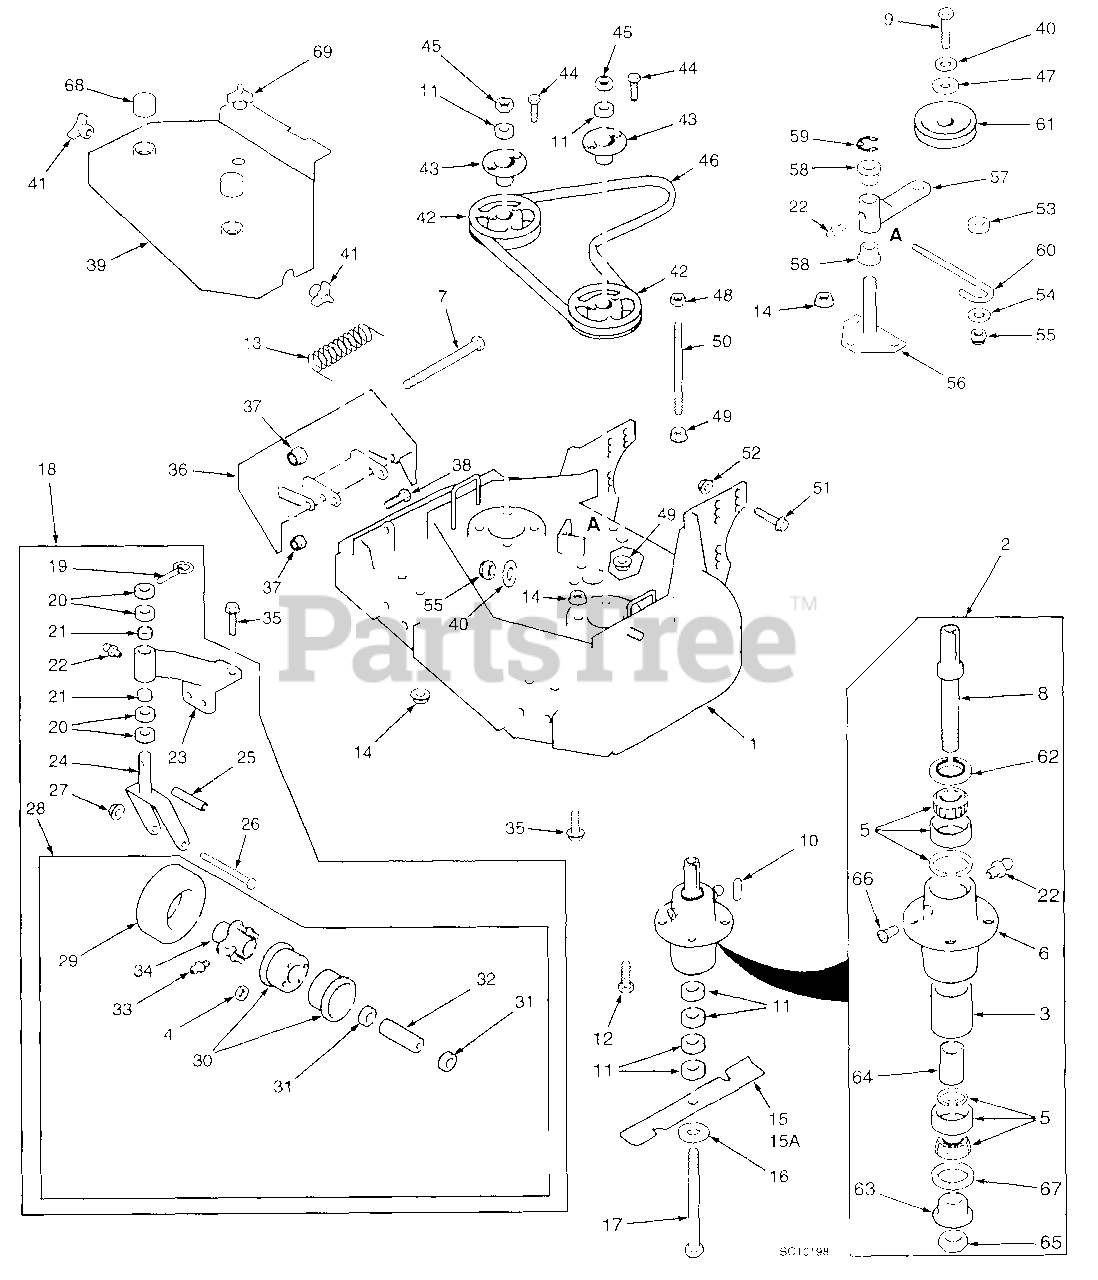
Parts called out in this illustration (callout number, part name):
1	Cutter Deck
2	Cutter Spindle Assy.
3	Spacer, Outside
4	Tapered Nut, 5/16-24
5	Tapered Bearing (Two)
6	Spindle Housing
7	Bolt, 8/16-18 x 4-1/4" Hex Head
8	Spindle Shaft
9	Bolt, 3/8-16 x 3-1/2" Hex Head
10	Key, 1/4 x 1/4 x 2"
11	Spacer, Cutter Blade - Small
12	Bolt, 5/16-18 x 1-1/4" Hex Head
13	Spring, Chute Return
14	Nut 5/16-18 Serrated Flange
15	Cutter Blade, 18"
15A	Gutter Blade, 18 Hi Lift
16	Flatwasher, 5/8 W
17	Hex Hd. Bolt, 5/8-11 x 9-1/2"
18	Caster Assembly
19	Quick Pin
20	Spacer, Caster Yoke, 1/2" long
21	Bronze Bearing
22	Grease Fitting
23	Support Assembly
24	Caster Yoke
25	Sleeve, Caster Wheel Bearing
26	Hex Hd. Bolt, 1/2-13 x 5-1/2"
27	Elastic Stop Nut, 1/2-13
28	Wheel Assy.
29	Tire only, Caster Wheel
30	Rim Pair, Caster Wheel
31	Retainer, Bearing, Caster Wheel
32	Roller Bearing, Caster Wheel
33	Grease Fitting, 45° 1/4-28
34	Hub Assembly
35	Cpscrw,5/16-18 x 3/4" Ser. Flg. Hex Head
36	Discharge Chute
37	Hex Nut, 5/16-18 Elastic Stop
38	Hex Hd Bolt, 5/16-18 x 1"
39	Belt Cover Assy
40	Flat Washer, 3/8" Special
41	Wing Nut, 3/8-16
42	Pulley
43	Tapered Hub
44	Hex Hd. Bolt, 1/4-20 x 3/4"
45	Hex Nut, 5/8-11
46	Belt, Blade Drive
47	Spacer
48	Hex Nut, 3/8-16 Center Locknut
49	Nut, 3/8-16 Serrated Flange
50	Support, Belt Cover
51	Cpscrw, 7/16-14 x 1 "Ser. Flg. HH
52	Nut, 7/16-14 Serrated Flange
53	Spacer, J-Hook
54	Washer, 3/8 x 1-1/2 x 16 GA
55	Elastic Stop Nut, 3/8-16
56	Idler Pivot
57	Idler Arm Assy
58	Bronze Bearing
59	Retaining Ring, 1-1/8" Ext. "E"
60	J-Hook
61	Idler Pulley, Belt Clutch
62	Seal, Cutter Spindle
63	Spindle Bushing
64	Spacer, Inside
66	Relief Fitting, Cutter Spindle
67	Seal, Cutter Spindle
68	Spindle Shield
69	Wingnut, 3/8 (Small)
